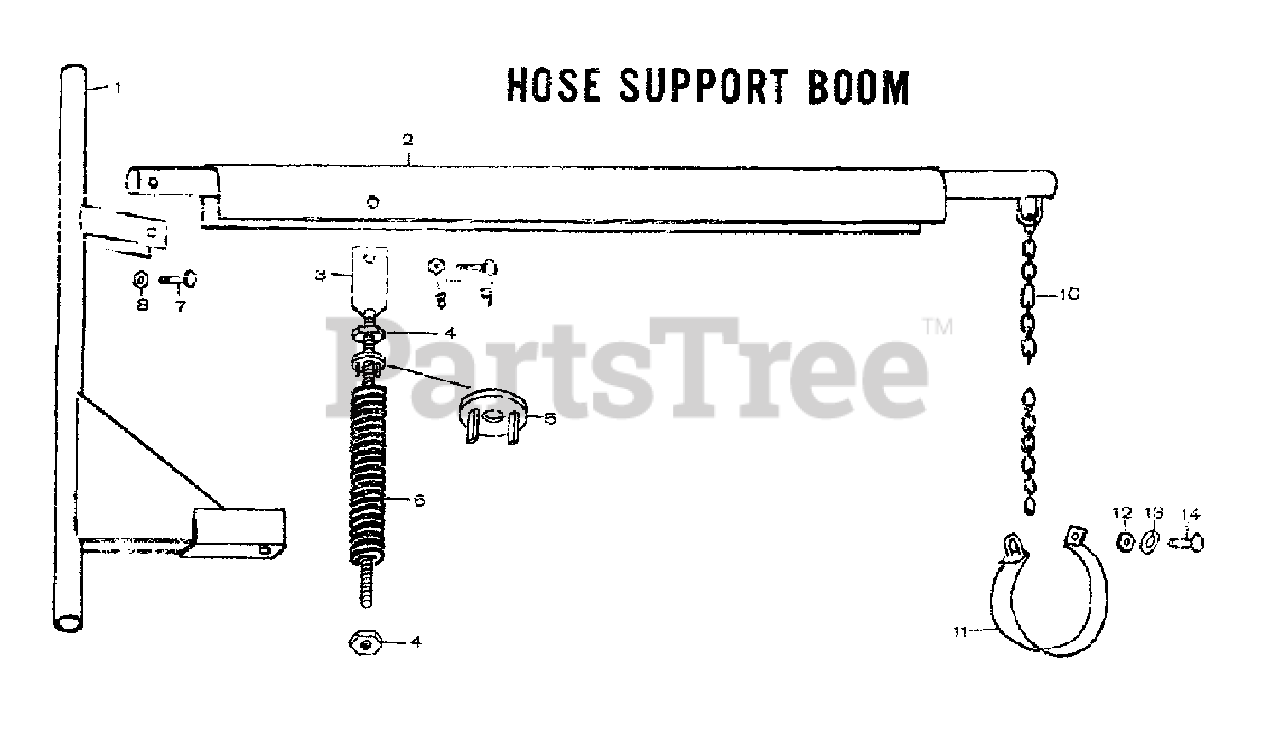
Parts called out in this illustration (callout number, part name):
1	Boom vertical member
2	Boom horizontal member
3	Threaded spring guide
4	3/4 nut
5	3/4 flat washer
6	Boom coil spring
7	1/2 x 3 hex bolt
8	1/2 lock nut
9	1/2 x 3 hex bolt
10	Boom chain
11	Hose support band – 12
11	Hose support band – 16
12	5/16 hex nut
13	5/16 lock washer
14	5/16 x 3 1/2 hex bolt
